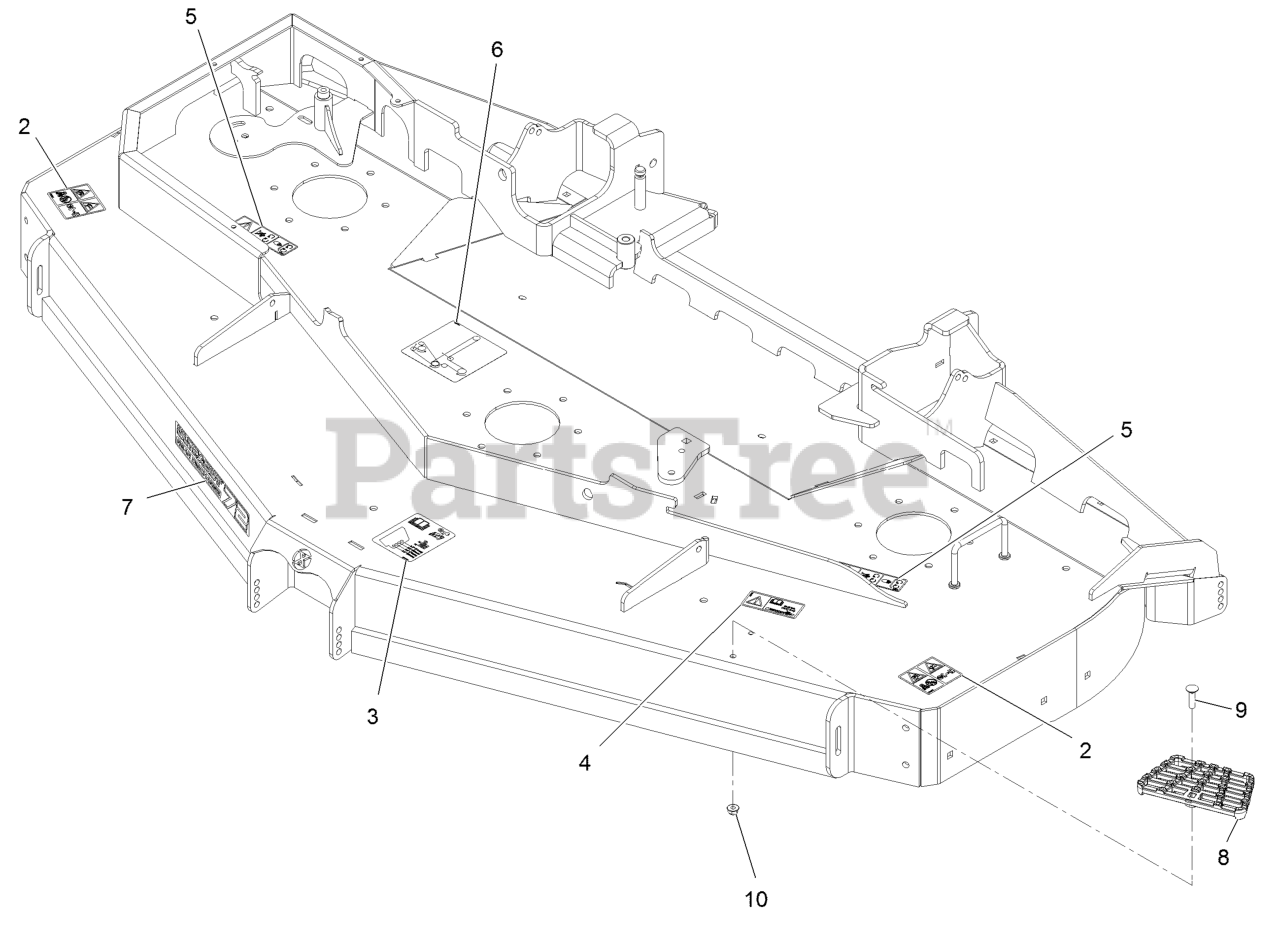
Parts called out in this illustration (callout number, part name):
2	DECAL-DANGER, THROWN OBJECT
3	DECAL-ROLLER, ANTI-SCALP
4	DECAL-BOLT TORQUE
5	DECAL-COVER, MISSING
6	DECAL-ROUTING, BELT
7	Decal, 72Rd
8	STEP-DECK
9	Bolt-Carriage 5/16-18 X 1 1/4
10	NUT-HF, NI
